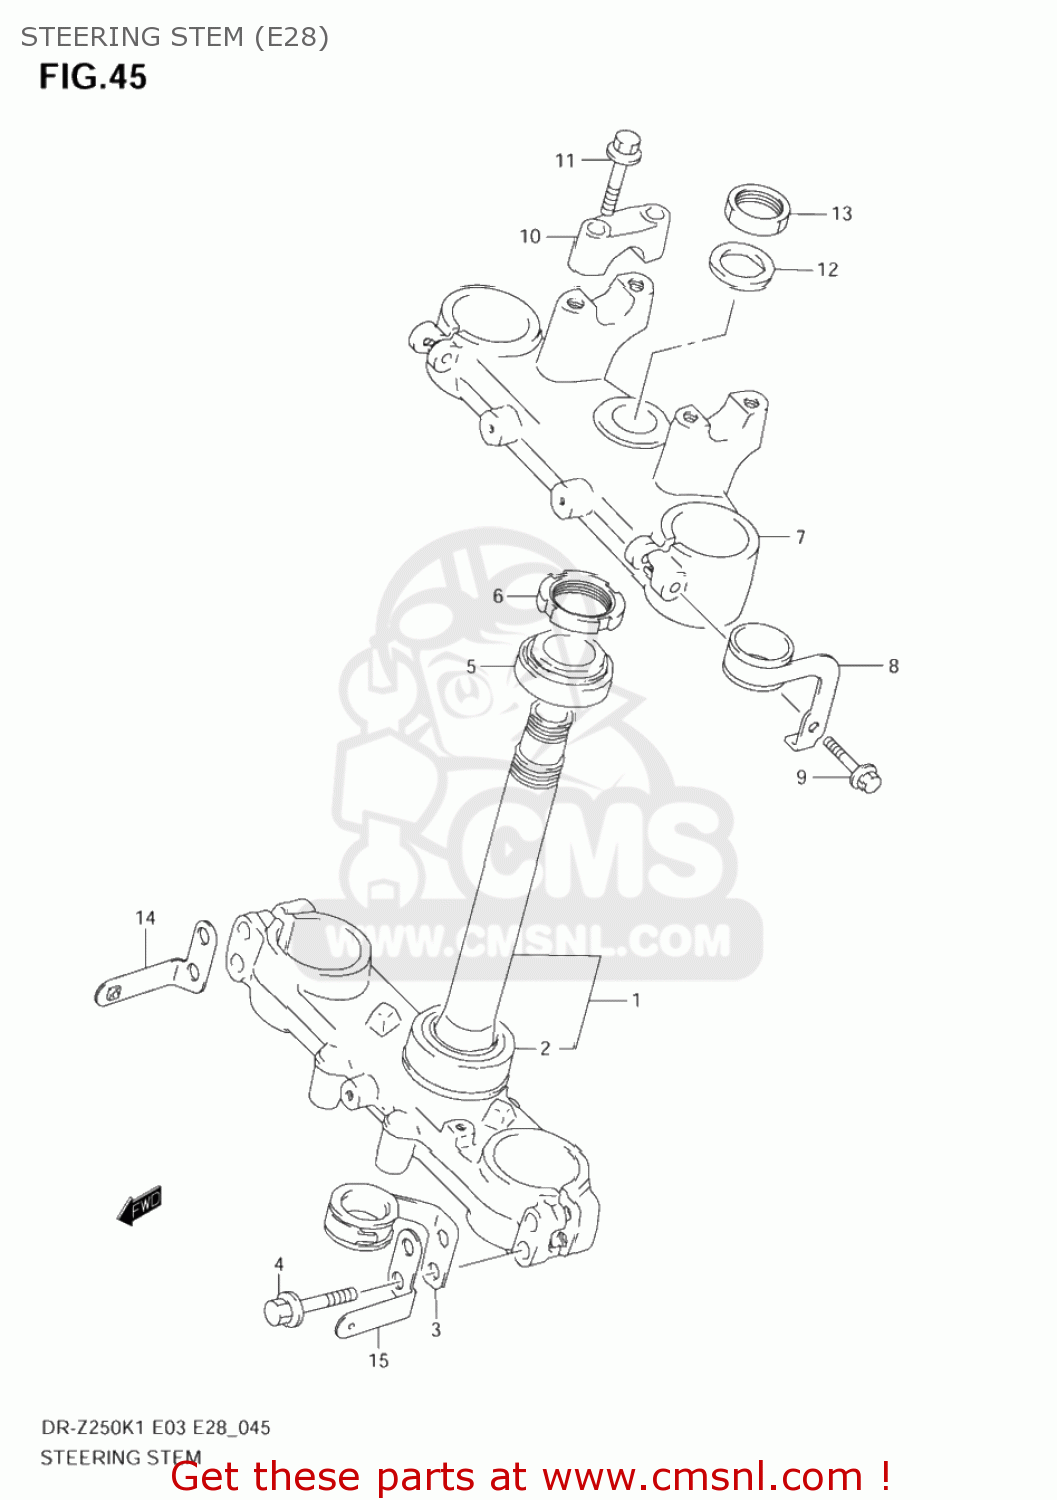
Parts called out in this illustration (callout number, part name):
1	STEM,STEERING
2	BEARING(30X52X16)
3	GUIDE,CABLE LWR,L
4	BOLT
5	BEARING(30X52X16)
6	NUT,STEERING
7	HEAD,STEERING STEM
8	GUIDE,CABLE UPR,L
9	BOLT
10	HOLDER,HANDLE
11	BOLT,HANDLE HOLDER
12	WASHER,STEM HEAD
13	NUT,STEM HEAD
14	BRACKET,FR SIDE RR,R
15	BRACKET,FR SIDE RR,L
